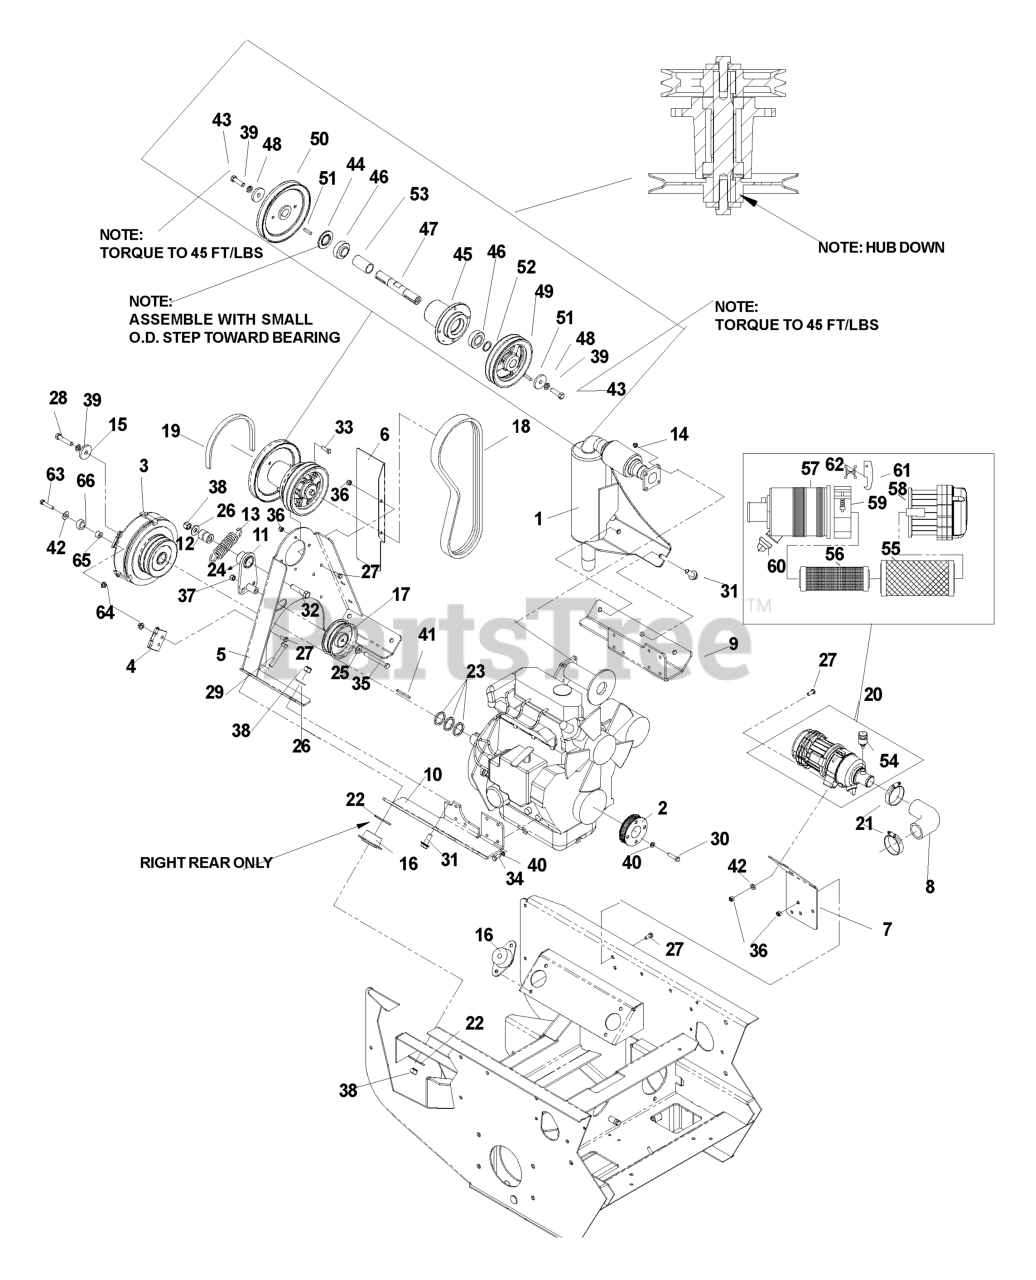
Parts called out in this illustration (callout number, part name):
1	MUFFLER TURBO
2	ENGINE SHEAVE
3	ELECTRIC CLUTCH
4	RESTRAINT KIT
5	JACKSHAFT MOUNT WELDMENT
6	HEAT SHIELD
7	MOUNTING BRACKET
8	AIR FILTER HOSE
9	ENGINE MOUNT-LT
10	ENGINE MOUNT-RT
11	ARM WELDMENT
14	NUT M8-1.25 STOVER
15	SPINDLE WASHER
18	BELT, PRIMARY BZ
19	ENGINE, BELT MULE
20	AIR FILTER ASSY
21	CLAMP, AIR HOSE
22	WASHER, HEAVY
23	BUSH 1-1/8 X 10 GA ZD
24	GREASE ZERK LONG
25	WASHER 3/8 SAE FLAT
26	WASHER 1/2 FLAT
27	HCS 5/16C X 3/4
28	BOLT 7/16F X 2 1/2
29	HCS 1/2C X 2 3/4
30	HTB M8-1.125 X 25MM
31	HCS 1/2C X 1 1/4 SERRATED HEAD
32	HEX SCREW 1/2-13 X 2.5" GR 5
33	HCS 5/16C X 1
35	HCS 3/8-16 X 3-1/2 GR5 ZD
36	NUT 5/16 NYLOC
37	NUT 3/8-16 NYLOC
38	NUT 1/2-13 HEX NYLOC ZD
39	WASHER 7/16 LOCK
40	WASHER.LOCK.HVY.HLCL.SPR.5/16
41	KEY 1/4 SQ X 2-1/2
42	WASHER 5/16 FLAT
43	HCS 7/16F X 1 1/2
44	COMBO SPACER
45	HOUSING, DIE CAST
46	BEARING
48	SPINDLE WASHER
51	KEY 1/4 SQ X 1 1/8
52	BUSHING.MACHINE.18.GAUGE
55	AIR FILTER
56	SAFETY ELEMENT
57	BODY, STRAIGHT
58	PRECLEANER ASM
59	MOUNTING BRACKET
63	HCS 5/16C X 1 1/4
64	NUT 5/16C WHIZ
